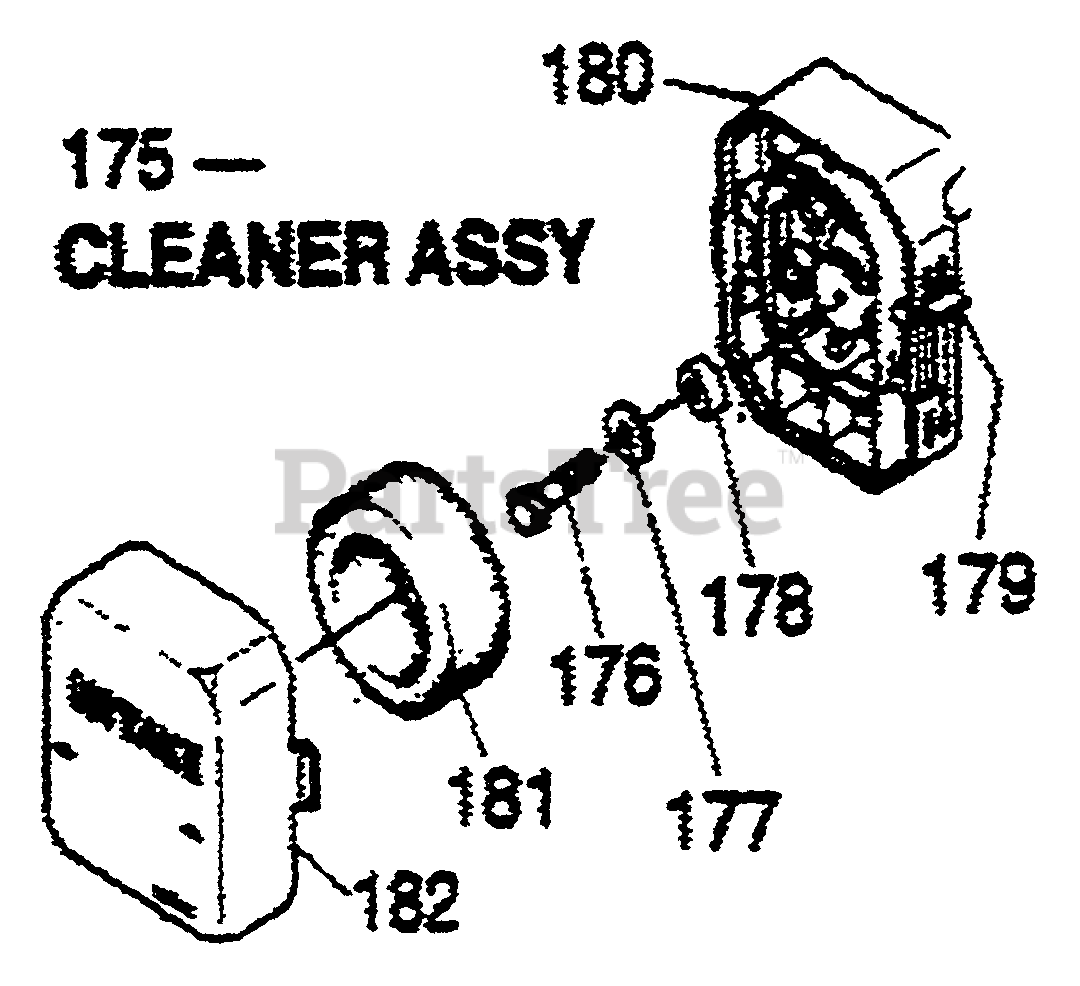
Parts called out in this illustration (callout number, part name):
175	CLEANER ASSY
176	SCREW & WASHER
179	LEVER, CHOKE
180	BODY, CLEANER
182	COVER, CLEANER
